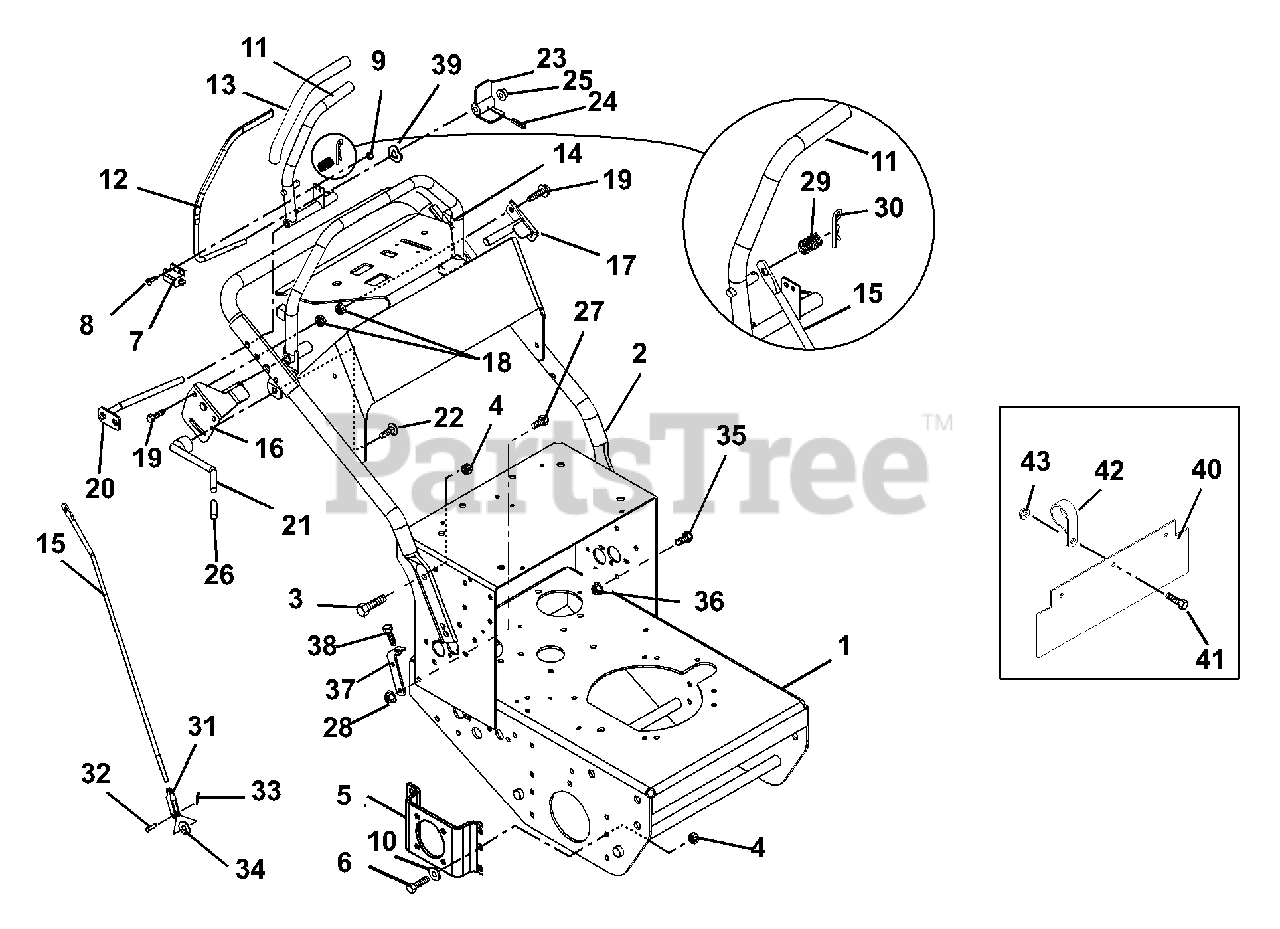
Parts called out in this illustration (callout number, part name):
1	KIT-FRAME W/DECALS
2	KIT-HANDLEBAR/DECALS HR15-ERGO
3	@BLT-HEX .38-16X1.00 GR5 YWZC
4	@NUT-LK-NYL .38-16 YWZC
5	BRACKET, WHEEL MOTOR LH
5	BRACKET, WHEEL MOTOR RH
5	BRKT, WHEEL MOTOR LH
5	BRKT, WHEEL MOTOR RH
6	@BLT-HEX .38-16X1.00 GR5 YWZC
7	SWITCH- DOUBLE POLE N.O./N.O.
7	SWITCH,INTERLOCK
8	@SCR-MCH 10-24X.75 HWH YWZC
9	@NUT-LK-NYL 10-24 W/INSRT YWZC
10	@WSHR-FL-STL.406X.812X.065 YWZ
11	WMT-LEVER-RH SPEED CONTROL-HYD
11	WMT-LEVER-LH SPEED CONTROL-HYD
12	LEVER - OPERATOR PRESENCE
13	GRIP - HANDLEBAR
14	WMT - SPEED CONTROL STOP
15	ROD - STEERING - HYDRO
16	WMT-CONTROL STOP LIMITER-RH
16	WMT - CONTROL STOP LIMITER -RH
17	WMT-CONTROL STOP LIMITER-LH
18	@NUT-LK-TOP-FLG .31-18 YWZC
19	@BLT-HEX .31-18X1.75 GR5 YWZC
20	WMT - SPEED CONTROL PIVOT - RH
20	WMT - SPEED CONTROL PIVOT - LH
21	LEVER - CONTROL STOP LOCK
22	BLT-RDHDSQSHK.31-18X.75 GR2 YW
22	@BLT-RDHDSQNK .38-16X.75 G5YZ
23	ACTUATOR - SWITCH
24	PIN-ROLL .125X.75
25	NUT-PUSH .312
26	GRIP,HAND CLUTCH LEVER
27	@BLT-HEX .38-16X.75 GR5 YWZC
28	@NUT-LK-TOP-FLG .38-16 YWZC
29	SG-COMP .045X.600X.750 WLD7.5
30	PIN-HAIR INT .08X.18X1.18 YWZC
31	YOKE, .312-24 X 2.25
32	PIN-CLEV .31X.937 FLHD YWZC
33	PIN-HAIR, ENDRIES #25 YWZC
34	WSHR-FL-STL .328X.87X.179 YWZC
35	@BLT-HEX .31-18X1.00 GR5 YWZC
36	@NUT-SPNLK-FLG .312-18 YWZC
37	WMT - REVERSE ADJUST BRACKET
38	@BLT-HEX .31-18X1.25 GR5 YWZC
39	WAVE WASHER .390X.655X.110
40	GUARD - DEBRIS
41	@BLT-HEX .38-16X.75 GR5 YWZC
42	CLAMP, COUSHIONED STEEL REV
43	@NUT-LK-TOP-FLG .38-16 YWZC
